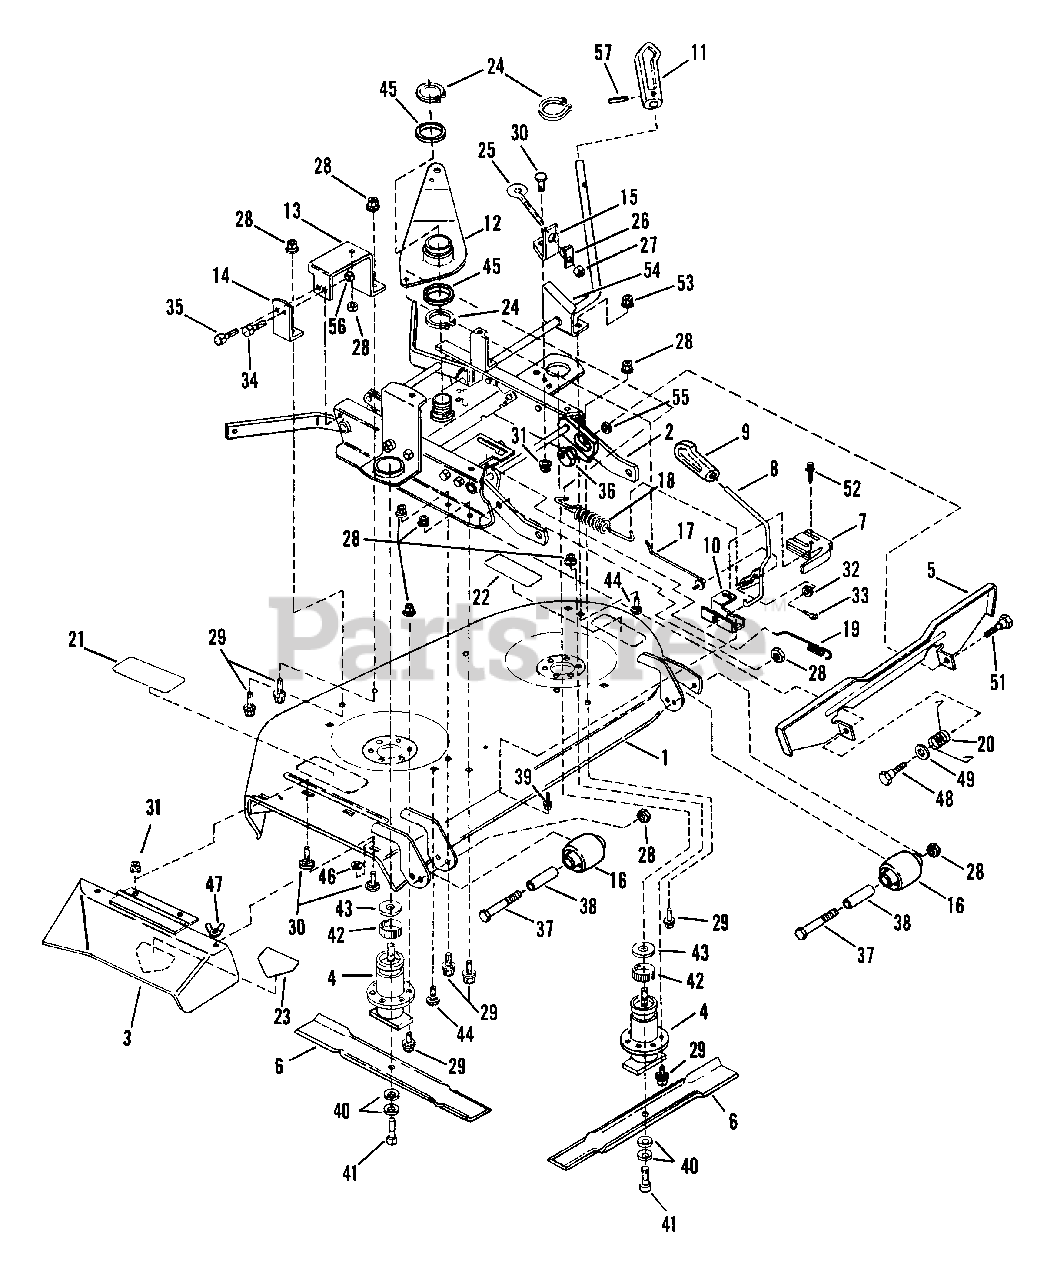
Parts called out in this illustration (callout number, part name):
1	ASSEMBLY, Deck
2	ASSEMBLY, Rail
3	ASSEMBLY, Side Chute
4	ASSEMBLY, Spindle
5	ASSEMBLY, Pedal
6	BLADE, 21"
7	SWITCH
8	LEVER, Blade Engage
9	GRIP, Handle
10	BRACKET
11	GRIP, Height Adjustment Lever
12	IDLER ARM
13	SUPPORT, Idler
14	BRACKET
15	ANCHOR
16	ROLLER
17	ROD, Idler
18	SPRING,Belt
19	SPRING,Latch
20	SPRING, Pedal
21	DECAL, Caution (Rotating Blades)
22	DECAL, Caution (Rotating Blades)
23	DECAL, Danger (Keep Hands & Feet Away)
24	RING, 2" External Retaining
25	EYE-BOLT
26	T-NUT
27	NUT, 1/4-20 Hex
28	NUT, 3/8-24 Hex Lock
29	SCREW, 3/8-24 x 3/4" Hex Head Cap
30	BOLT, 5/16-18 x 5/8" Carriage
31	NUT, 5/16-18 Hex Flange Lock
32	WASHER, 1/4 Flat
33	PIN, 3/32 x 3/4" Cotter
34	SCREW, 3/8-16 x 3/4" Hex Head Cap
35	SCREW, 3/8-16 x 1" Hex Head Cap
36	ECCENTRIC, Leveling
37	SCREW, 3/8-24 x 3 3/4" Hex Head Cap
38	SPACER
39	SCREW, 1/4-20 x 5/8" Self-Tapping
40	WASHER, Cone
41	SCREW, 3/8-24 x 1" Hex Head Cap
42	RING, Tolerance
44	BOLT, 3/8-16 x 3/4" Carriage
45	WASHER, Nylon, 2" I.D.
46	RETAINER, 5/16 Bolt
47	NUT, 5/16-18 Wing
48	BOLT, 3/8-24 x 9/16" Shoulder
49	WASHER, 1/2 Flat
51	BOLT, 3/8-24 x 3/4" Shoulder
52	SCREW, #10-32 x 1" Self-Tapping
53	NUT, 3/8-16 Hex Lock
54	BRACKET, Height Indicator
55	WASHER, 3/8 Internal Tooth Lock
56	NUT, 3/8-16 Hex Lock
57	ROLL-PIN
